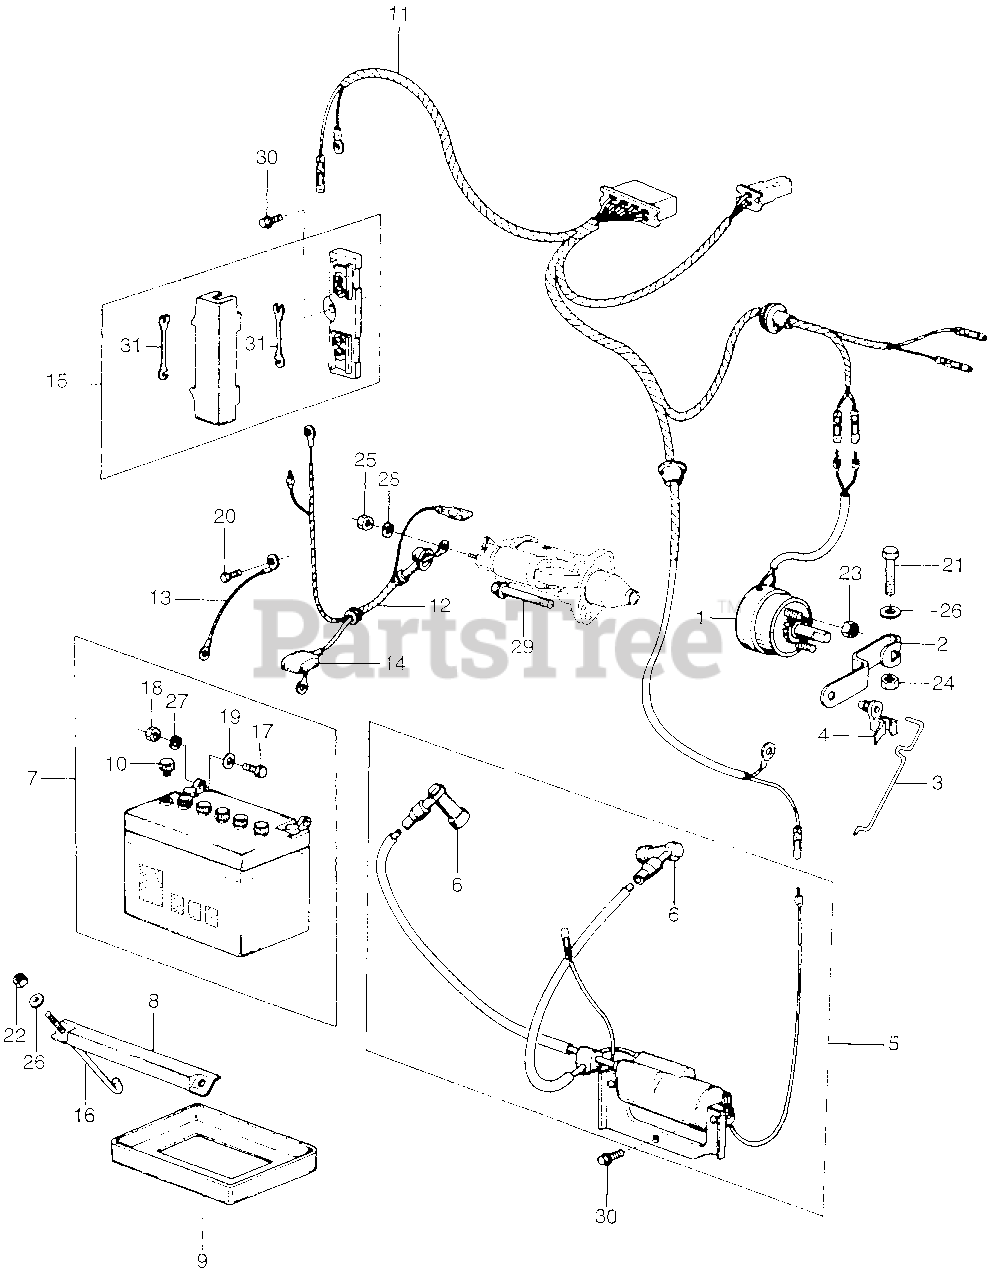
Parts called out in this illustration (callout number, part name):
1	SOLENOID, THROTTLE (NOT AVAILABLE)
2	ARM, THROTTLE STOP
3	ROD, THROTTLE STOP
4	HOLDER, ROD (2MM) (NOT AVAILABLE)
5	COIL ASSY., IGNITION
6	CAP ASSY., NOISE SUPPRESSOR
7	BATTERY ASSY. (32A19RT-S) (YUASA)
7	BATTERY (26A19RT-S) (YUASA)
8	PLATE, BATTERY SETTING
8	PLATE, BATTERY SETTING (NOT AVAILABLE)
9	BOX, BATTERY
10	PLUG, VENT (YUASA)
11	WIRE HARNESS ASSY.
12	CABLE, STARTER
13	CABLE, GROUND (NOT AVAILABLE)
14	COVER, BATTERY TERMINAL
15	BOX ASSY., MAIN FUSE
16	BOLT, BATTERY SETTING (NOT AVAILABLE)
17	BOLT, BATTERY TERMINAL SETTING
19	WASHER, BATTERY TERMINAL SETTING (6MM)
20	BOLT, HEX. (6X10)
21	BOLT, HEX. (5X20)
22	NUT, HEX. (5MM)
23	NUT, HEX. (4MM)
24	NUT, HEX. (5MM)
25	NUT, HEX. (8MM)
26	WASHER, PLAIN (5MM)
27	WASHER, SPRING (6MM)
28	WASHER, SPRING (8MM)
29	BOLT, FLANGE (8X60)
30	BOLT, FLANGE (6X12)
31	FUSE G (45A)
